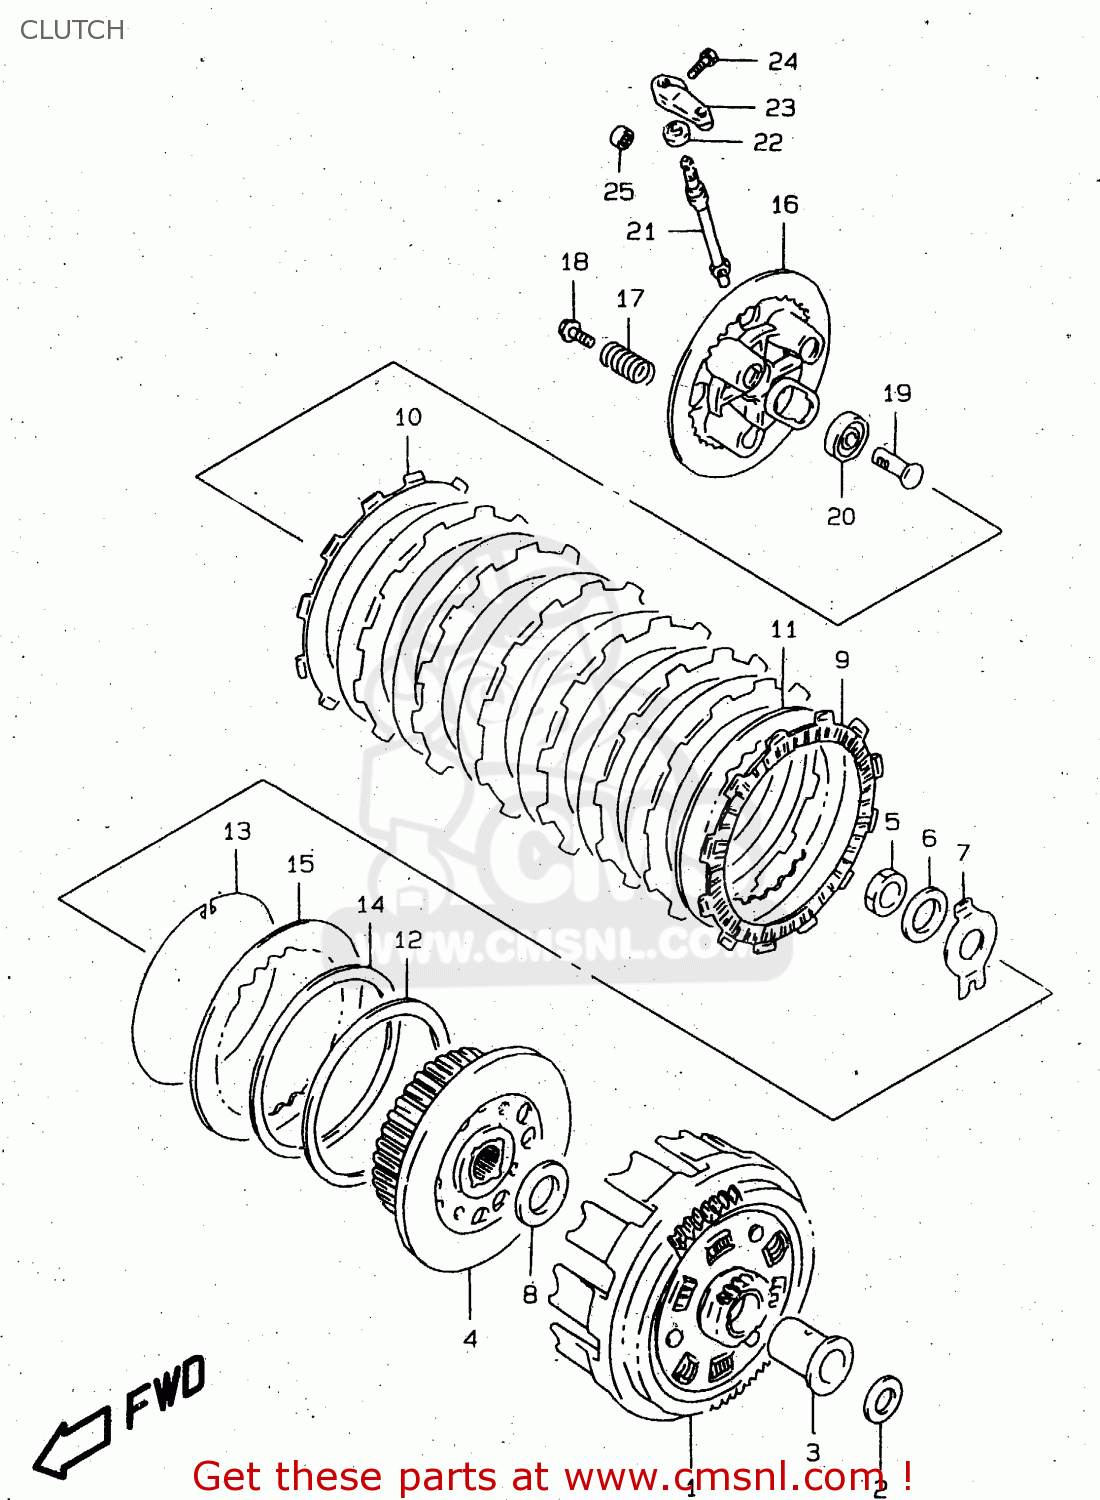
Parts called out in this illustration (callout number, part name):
1	GEAR ASSEMBLY,PRIMARY DRIVE
2	WASHER(22X32X3)
3	SPACER,PRIMARY DRIVEN GEAR
4	HUB,CLUTCH SLEEVE
5	NUT
6	WASHER
7	WASHER
8	WASHER(22X44X2)
9	PLATE,CLUTCH DRIVE (NAS)
10	PLATE,CLUTCH DRIVE (NAS)
11	PLATE,CLUTCH DRIVEN NO.1 (NAS)
12	SEAT,WAVE WASHER
13	RING,STOPPER
14	WASHER
15	PLATE,CLUTCH DRIVEN (NAS)
16	DISC,CLUTCH PRESSURE
17	SPRING
18	BOLT(6X16)
19	RACK,CLUTCH RELEASE
20	BEARING
21	PINION,CLUTCH RELEASE
22	SEAL,OIL(10X17X5)
23	ARM,CLUTCH RELEASE
24	BOLT
25	BEARING(12X16X10)
